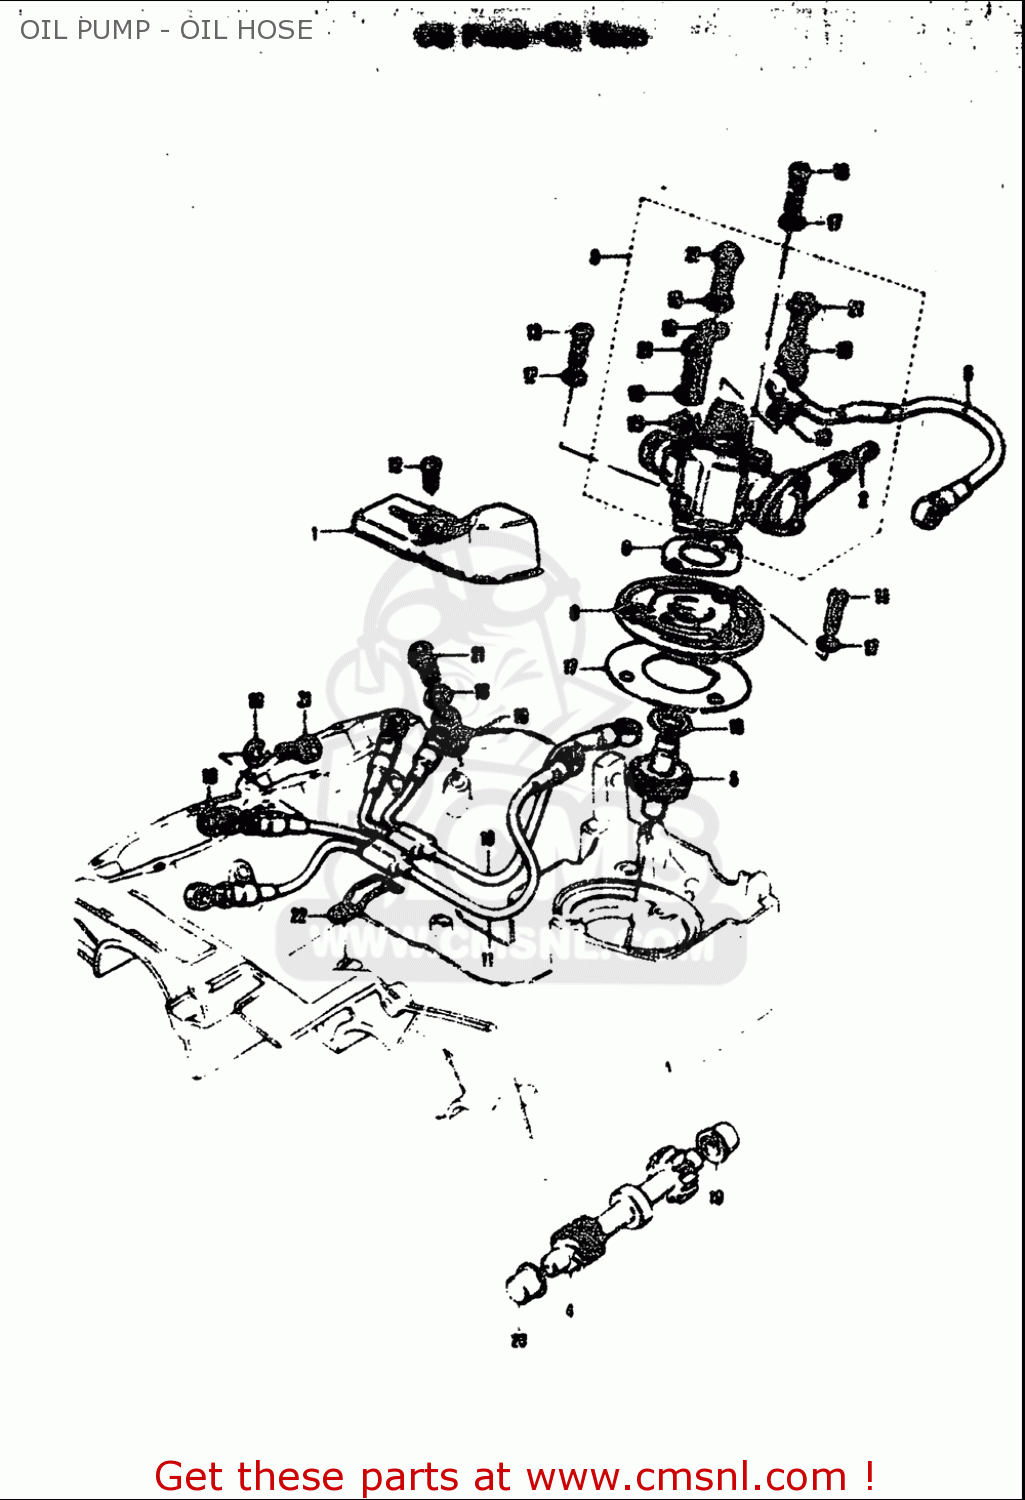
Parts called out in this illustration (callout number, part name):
2	TERMINAL, CABLE
7	GASKET,OIL PUMP GEAR CASE (MCA)
13	SCREW
16	SHIM(10X20X1)
17	WASHER
18	GASKET(6.2X11X1).2 (NAS)
21	UNION BOLT
